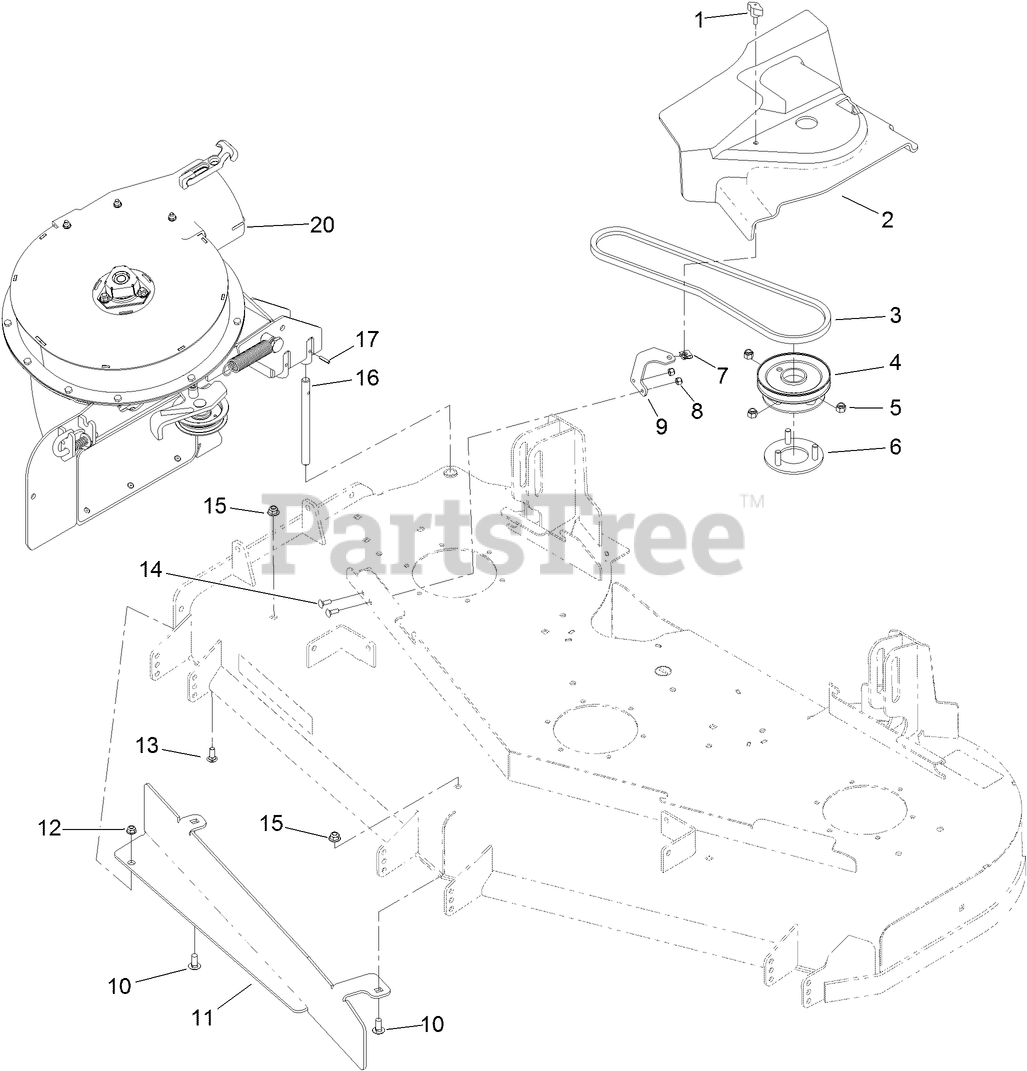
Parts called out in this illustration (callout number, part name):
2	COVER-BELT
3	BELT-V
4	PULLEY-BLOWER
5	NUT-LOCK, NI
6	MOUNT-PULLEY
7	NUT-SPEED
8	NUT-LOCK, NI
9	BRACKET-COVER, BELT
10	SCREW-CARR
11	BAFFLE-BAGGER
12	NUT-HF, NI
13	SCREW-CARR
14	BOLT-CARR
15	NUT-HF, NI
16	SHAFT-CATCHER, GRASS
17	PIN-ROLL
20	E-Z VAC BLOWER ASM
